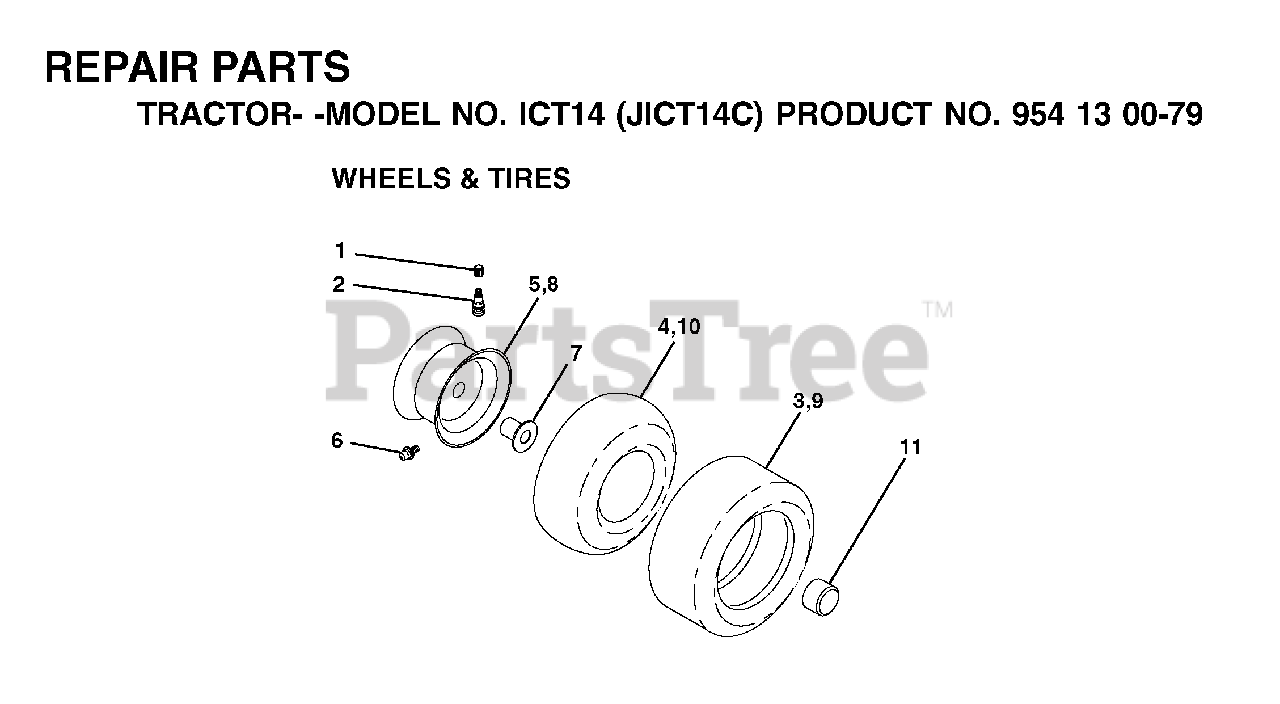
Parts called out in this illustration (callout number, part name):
1	VALVE CAP
2	VALVE STEM LT
3	TIRE HEAVY DUTY
4	TUBE.5.3/4.5/6
5	RIM ASM 6" FRONT SILVER
6	FITTING LT
7	BEARING T
8	RIM ASM 8" REAR SILVER
9	TIRE
10	TUBE
11	CAP, AXLE BLK
